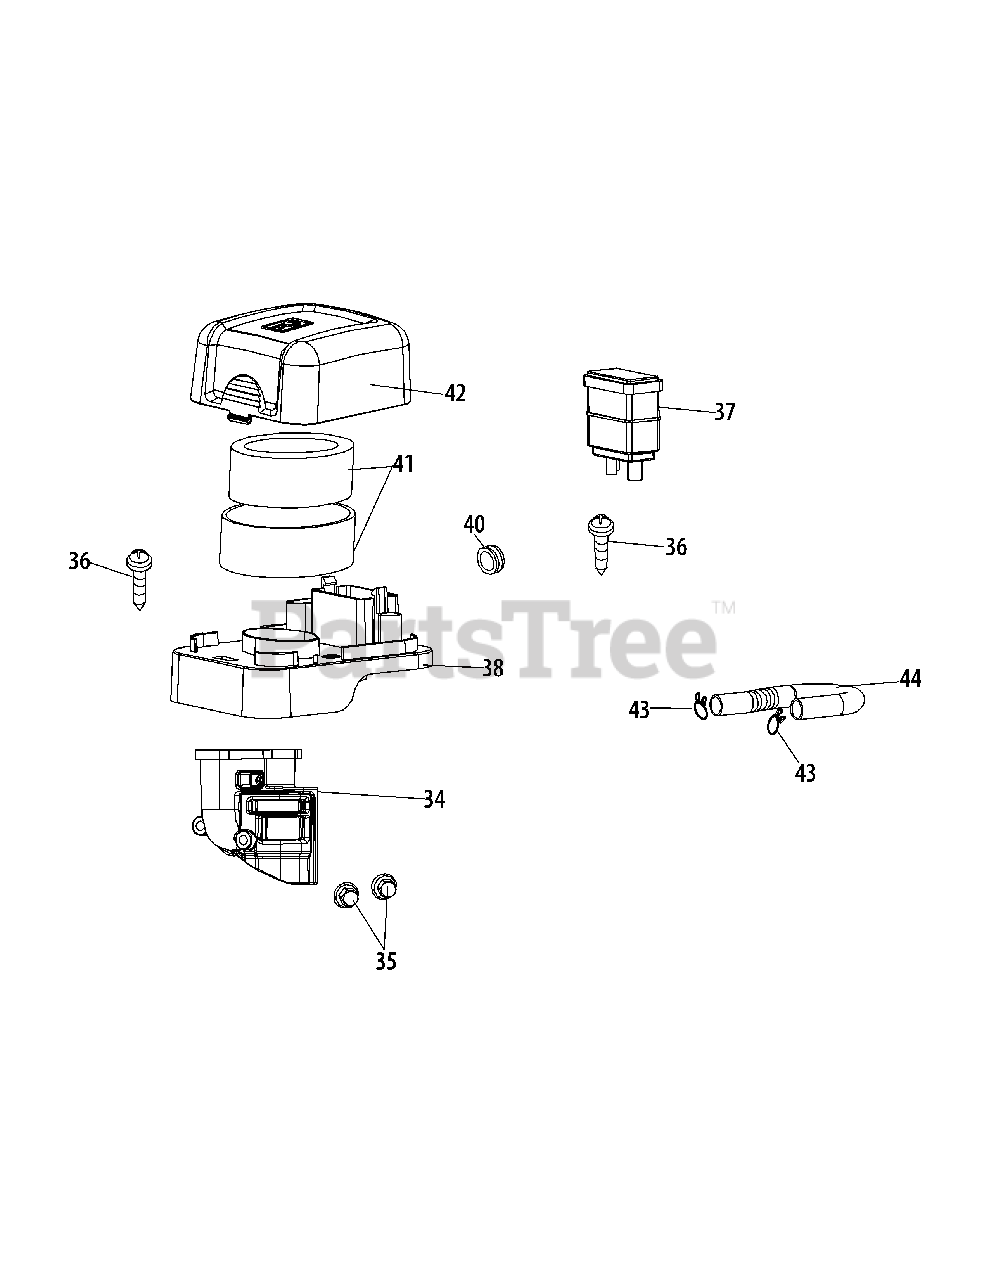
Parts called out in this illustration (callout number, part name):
34	Air Cleaner Housing
36	Self-Tapping Bolt4.2×20
37	Carbon Canister
38	Silencer Plate
40	Damper Gasket
41	Air Filter Assembly
42	Air Cleaner Cover
43	Venting House Clamp
44	Exhaust Piping
